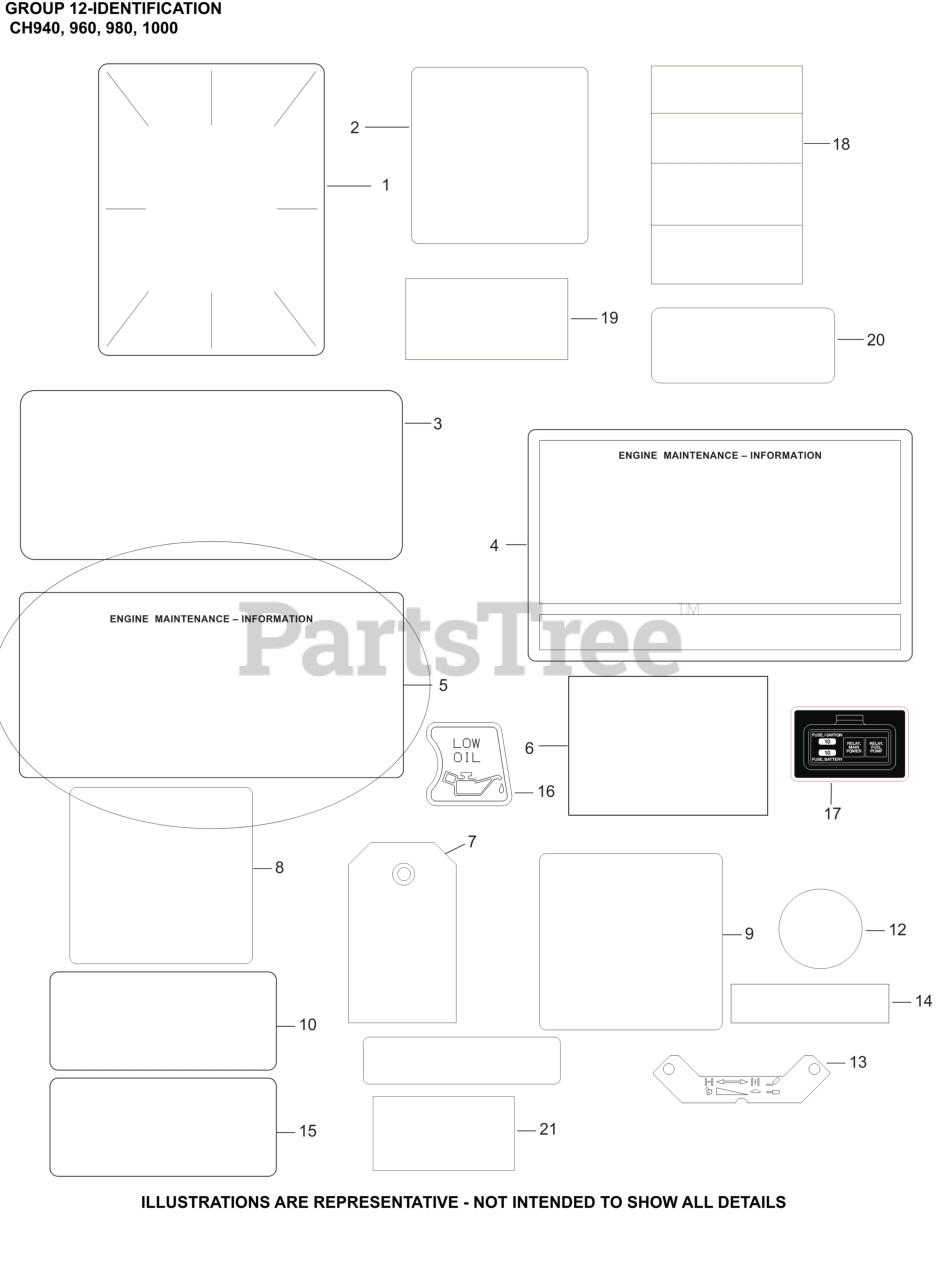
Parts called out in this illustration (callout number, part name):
1	LABEL, CLEAR LAMINATION
8	DECAL, 32.5 HP/999cc/CV-CH940
12	LABEL, GRASS SCREEN
16	DECAL, LOW OIL
21	DECAL, USA
